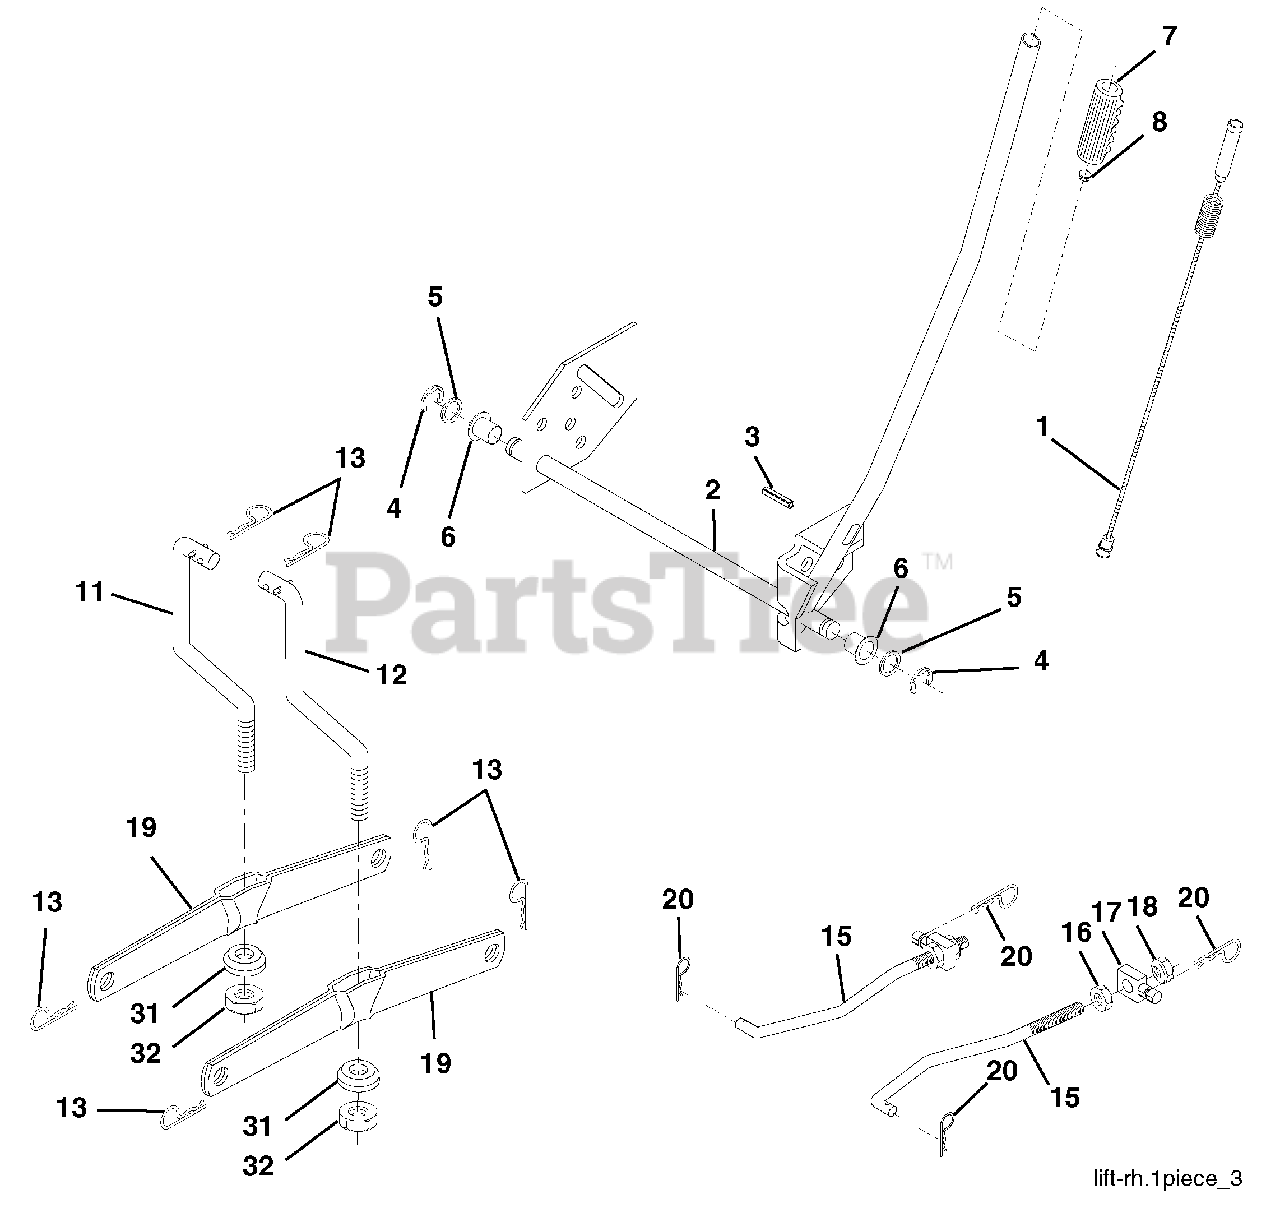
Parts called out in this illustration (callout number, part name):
1	Wire Asm Inner/Sprg w/plunger
2	Shaft Asm Lift RH
3	Pin Groove 1 500 Zinc
4	E Ring #5133-62
5	Washer 21/32 x 1 x 21 Ga.
6	Bearing Nylon Blk 629 Id
7	Grip Handle Bicycle Matte Blk
8	Button Plunger Black
11	Link Lift LH Fixed Length
12	Link Lift RH Fixed Length
13	Retainer Spring
15	Link Front
16	Nut Jam Hex 1/2-13 unc
17	Trunnion
18	Nut Lockw/Wsh 1/2-13 unc
19	Arm Suspension Rear
20	Retainer, Spring
31	Bearing Pvt Lift
32	Nut Crownlock 3/8-24
